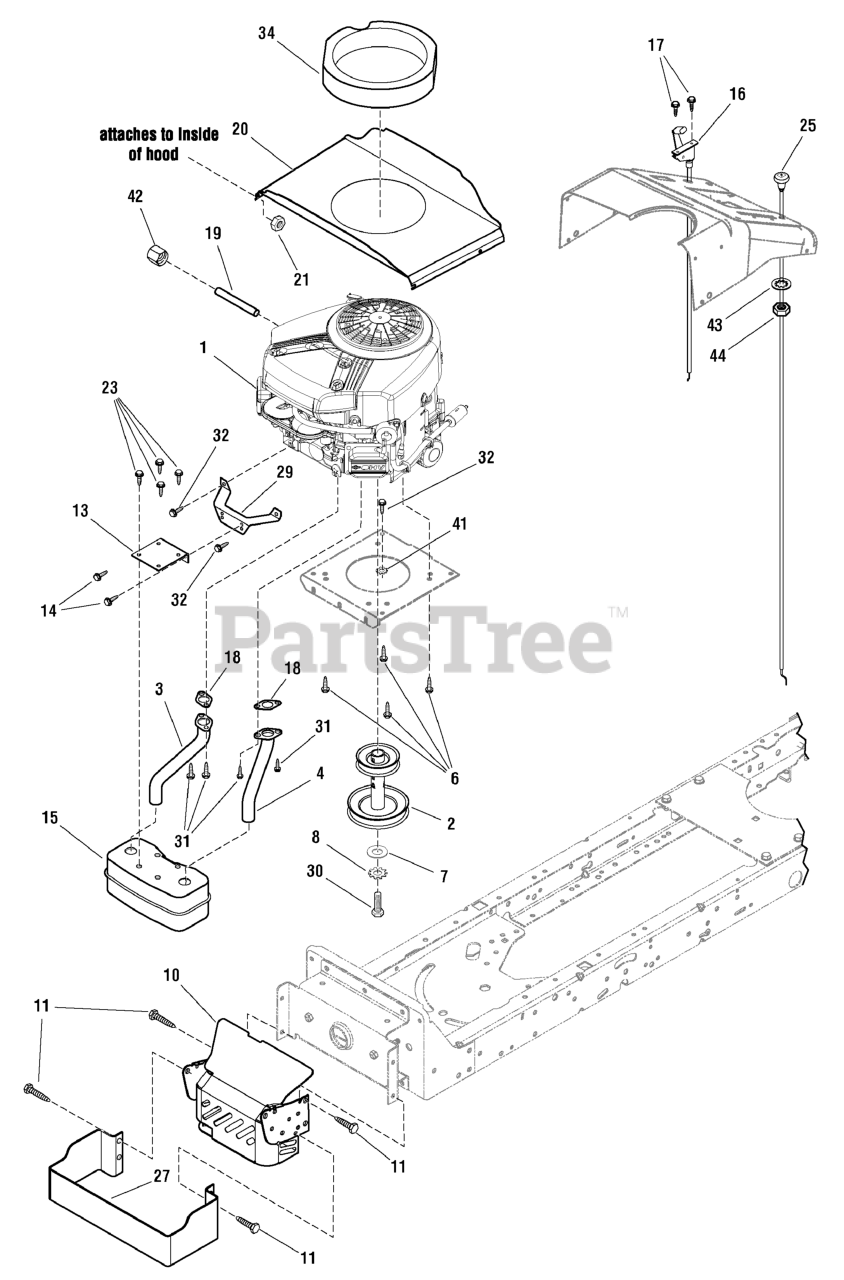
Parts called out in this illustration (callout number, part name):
1	ENGINE, 22.0HP Briggs & Stratton*
2	PULLEY, Stack
3	EXHAUST TUBE, Right
4	EXHAUST TUBE, Left
6	SCREW, Self Tap, 3/8-16 x 1-1/4
7	WASHER, Flat, 1/2
8	WASHER, Star, 1/2
10	HEAT SHIELD
11	SCREW, Hex Head 5/16-18 x 5/8
13	BRACKET, Muffler
14	SCREW, Hex 1/4-20 x 5/8
15	MUFFLER, Twin
16	THROTTLE CONTROL
17	SCREW, Self Tap #8 x 3/8
18	GASKET, Exhaust
19	NIPPLE, Pipe, 3/8 x 3 in
20	PLENUM, Murray
21	NUT, Keps Lock 1/4-20
23	SCREW, 1/4-14 x 3/8
25	CABLE, Choke
27	GUARD, Heat Shield, Front
29	BRACKET, Muffler Mounting
30	BOLT, Hex, 7/16-20 x 1-1/2
31	SCREW, 5/16-18 x 3/4
32	CAPSCREW, 5/16-18 x 3/4
41	WASHER, Star, 3/8
42	CAP, Pipe 3/8
43	LOCKERWASHER, External Tooth, 3/8
44	NUT, Hex, 3/8-16
